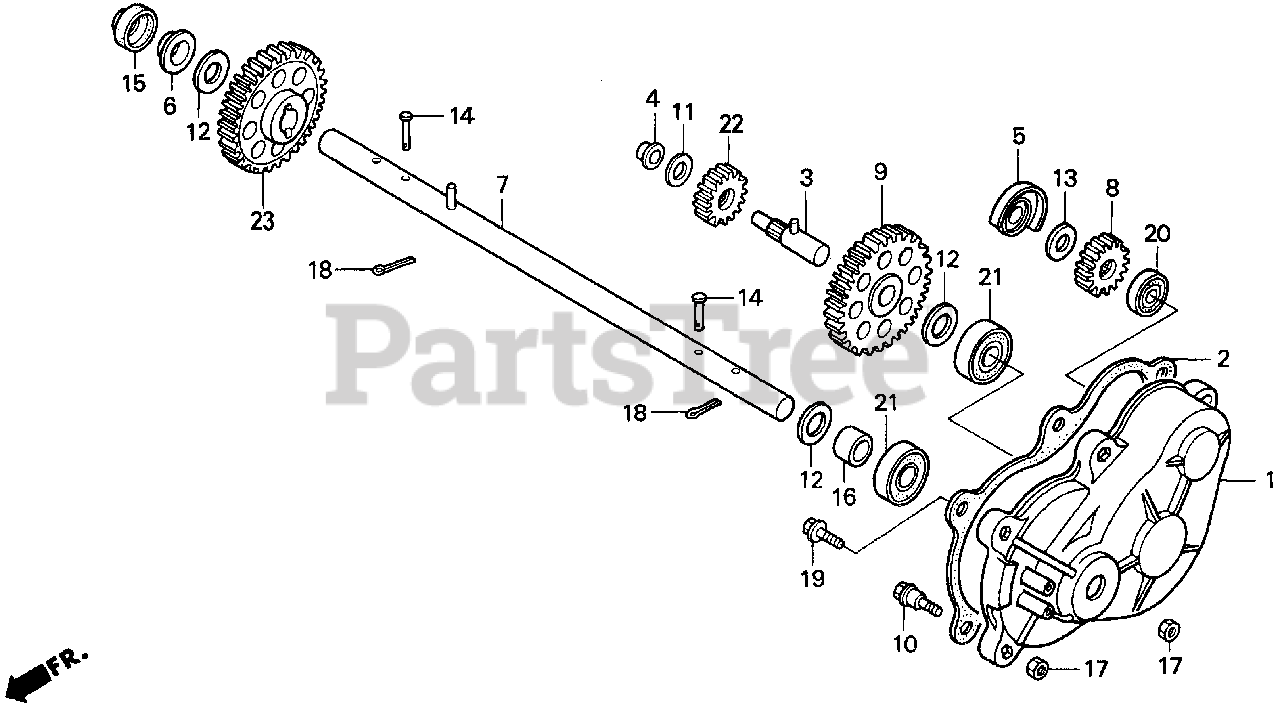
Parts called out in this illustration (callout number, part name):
1	CASE, R. TRANSMISSION
2	GASKET, TRANSMISSION CASE
3	COUNTERSHAFT
4	BUSH, COUNTERSHAFT
5	BUSH, CROSS SHAFT
6	BUSH, FINAL SHAFT
7	GEAR SET, FINAL
7	SHAFT, WHEEL
8	GEAR, DRIVE (19T)
9	GEAR, DRIVEN (48T)
10	BOLT, TRANSMISSION SETTING
11	WASHER, THRUST (12MM)
12	WASHER, DIFFERENTIAL GEAR
13	WASHER, THRUST (15X24X2)
15	DUST SEAL (20X34X7.5)
16	COLLAR, WHEEL SHAFT
17	NUT, HEX. (6MM)
18	PIN, SPLIT (3.0X25)
18	PIN, SPLIT (3.0X45)
19	BOLT, FLANGE (6X18)
20	BEARING, RADIAL BALL (6002UU)
21	BEARING, RADIAL BALL (6004UU)
22	GEAR, DRIVE (19T)
23	GEAR, DRIVEN (48T)
